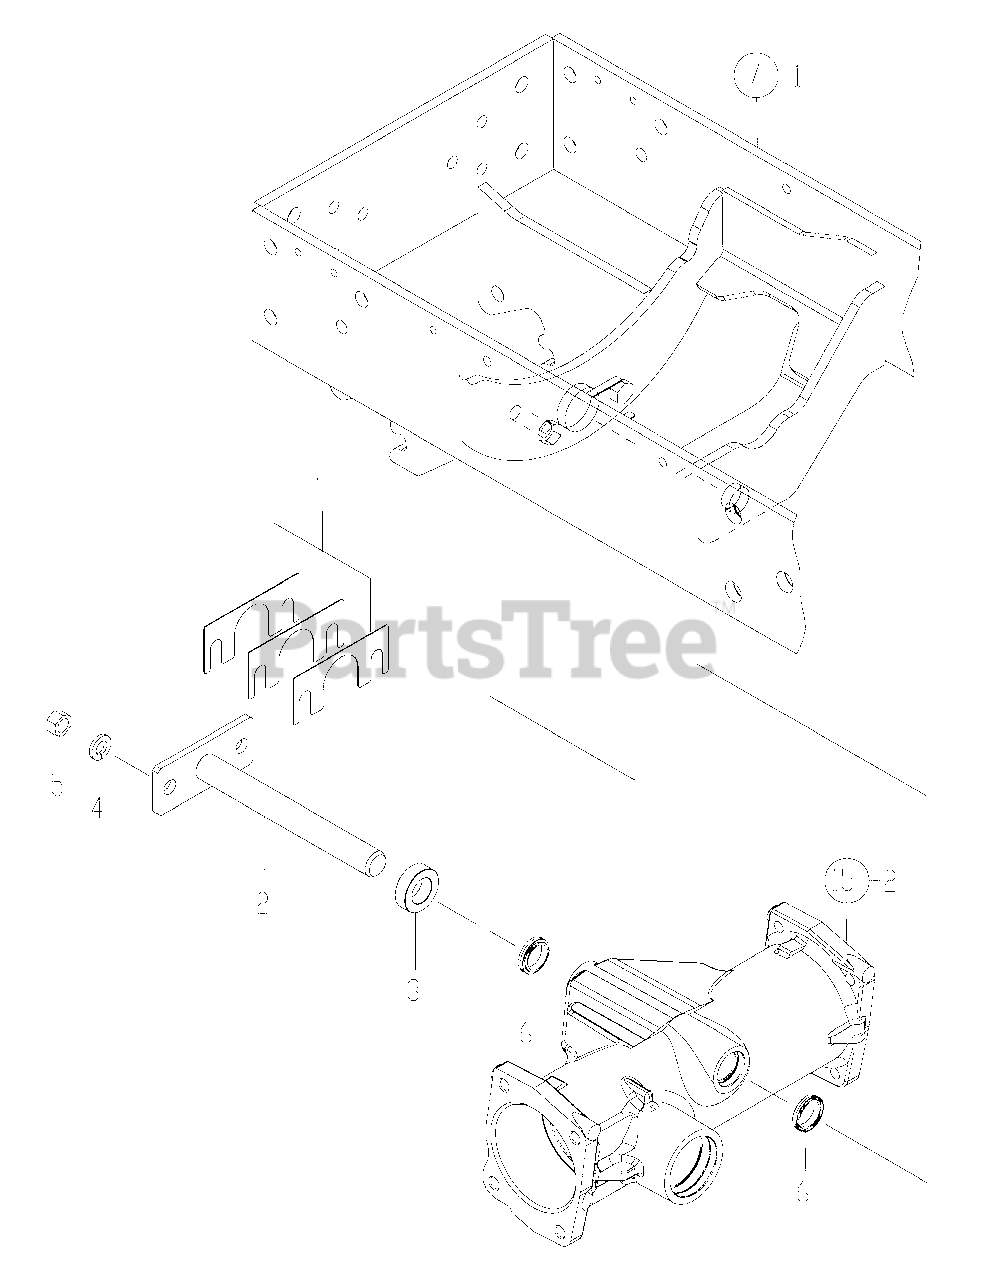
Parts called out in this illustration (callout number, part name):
1	SHIM SET, CENTER PIN
2	PIN ASSY, CENTER
3	COLLAR, 22X38X11.5
6	DUST SEAL 22 X 30 X 6
